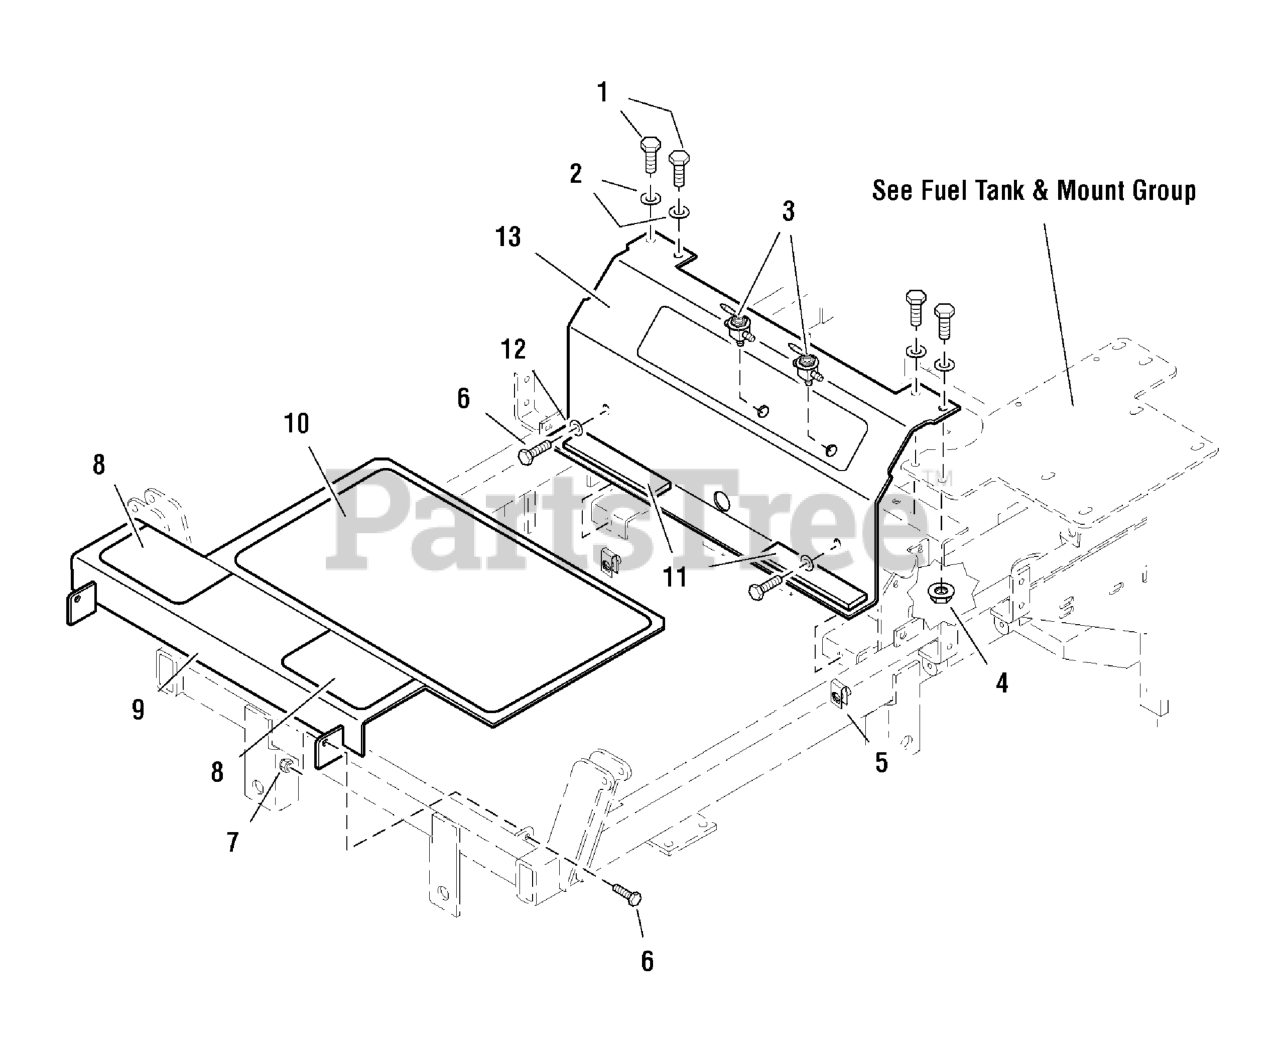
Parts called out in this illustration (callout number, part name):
1	BOLT, 3/8-16 X 1" GD5 CZ
2	WASHER, 3/8 SAE
3	VALVE, Fuel Shut Off
4	NUT, 3/8-16 Hex Serrated Flange
5	BODY CLIP, 5/16-18-7GA MATERIAL
6	BOLT, 5/16-18 X 3/4 GD5
7	NUT, 5/16-18 Hex Nylon Lock
8	SAFETY WALK
9	FLOOR PAN
10	SAFETY WALK, 11.50 X 19.00
11	RUBBER PAD
12	WASHER, 5/16" SAE
13	BRAKE COVER PANEL ASSEMBLY
